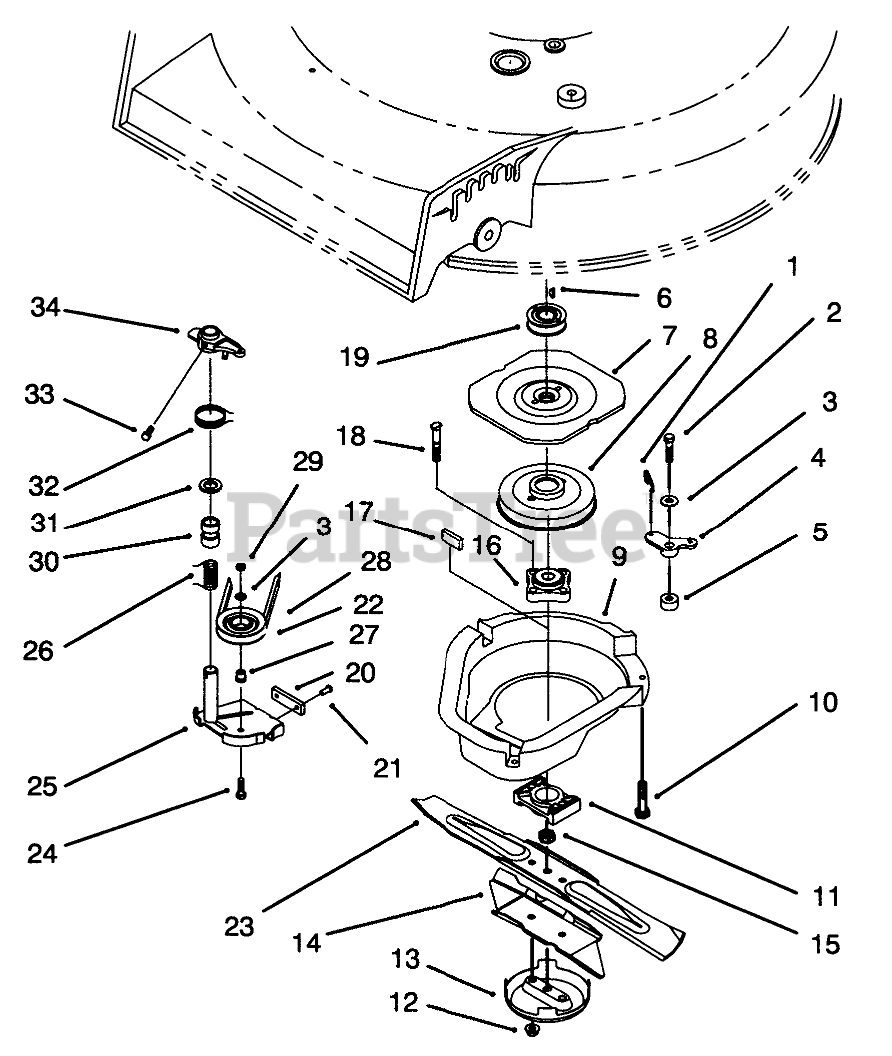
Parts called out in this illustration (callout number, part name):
1	LINK-CONTROL
2	SCREW-HH
3	WASHER-PLAIN
4	BELLCRANK
5	SLEEVE-BELLCRANK
6	KEY-WOODRUFF
7	Flywheel
8	Drum-Brake
9	SHIELD BBC
10	SCREW-HWH
11	SPACER-BLADE
12	NUT-LOCK
13	CUP-SCALP, ANTI
14	Accelerator
15	NUT-LOCK, NI
16	HUB ASM
17	DAMPENER-VIBRATION
18	BOLT-BLADE
19	PULLEY
20	Pad-Brake
21	.185 DIA X .375 RT +
22	PULLEY-IDLER
23	Blade
24	SCREW-HH
25	Brake Plate (Incl. Ref. # 20 & 21)
26	SPRING-TORSION
27	HUB-PULLEY, IDLER
28	V-BELT
29	NUT-LOCK, NI
30	BEARING
31	WASHER
32	SPRING-TORSION
33	SCREW-HH
34	LEVER
